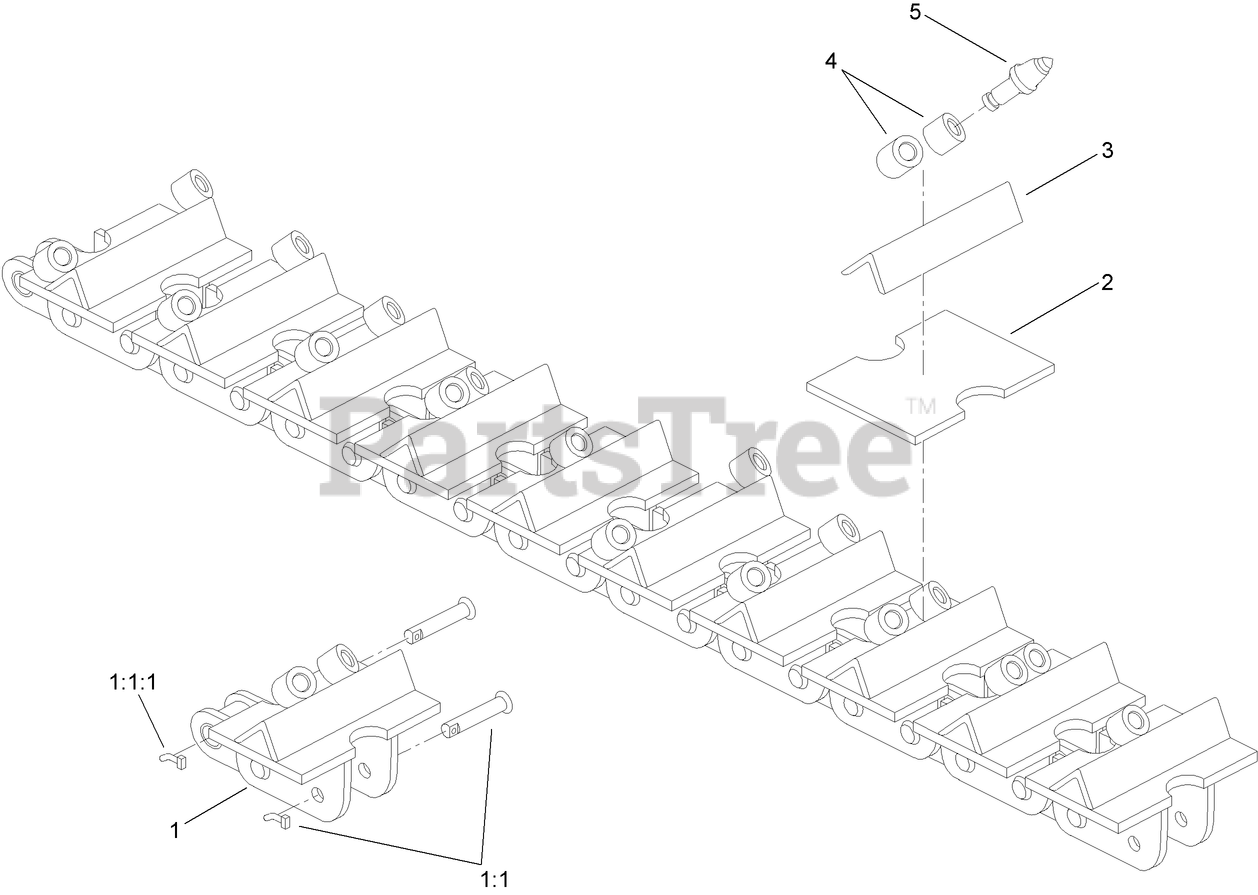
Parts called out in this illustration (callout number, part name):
1	CHAIN REPAIR LINK ASM
1:1	NOTCHED PIN AND KEEPER ASM
1:1:1	PIN-KEEPER
2	PLATE-H, WELD-ON
3	ANGLE-6 INCH
4	HOLDER-BIT
5	BIT-RETAINER, REAR
